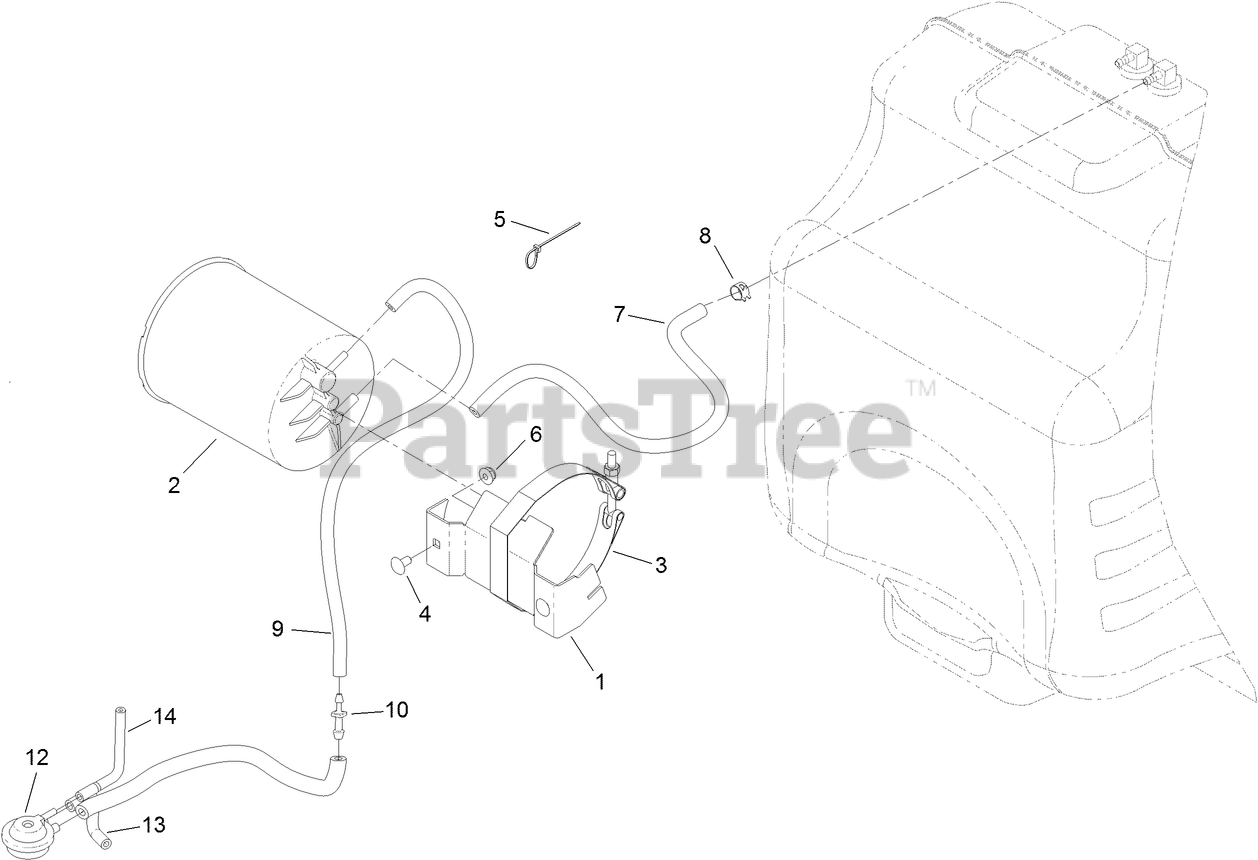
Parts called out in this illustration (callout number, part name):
1	BRACKET-CANISTER
2	CANISTER-CARBON, 1200CC
3	CLAMP, T-BOLT
4	SCREW-CARR
5	TIE-CABLE
6	NUT-HF
7	HOSE-FUEL
8	CLAMP-HOSE
9	HOSE-EMISSIONS
10	FITTING-STRAIGHT
12	VALVE-CONTROL, VACUUM
13	HOSE-VENT, FORMED
14	HOSE-VENT, FORMED
